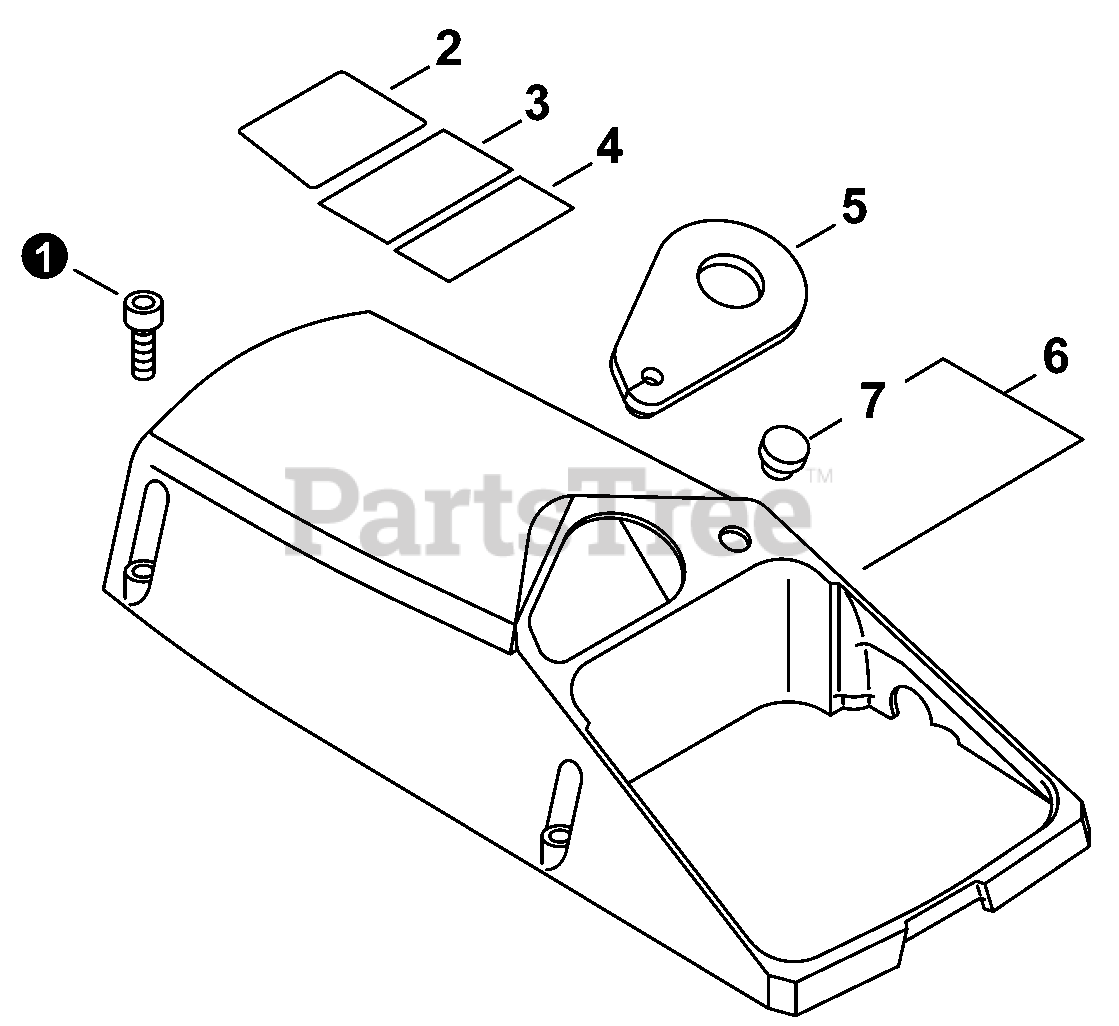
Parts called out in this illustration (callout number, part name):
1	BOLT 5x20
2	LABEL - UL - KICK BACK
3	LABEL - BAR & CHAIN
4	LABEL - KICK BACK WARNING
5	PLATE, GUIDE
6	ENGINE COVER KIT - GRAY
6	ENGINE COVER KIT - ORANGE
